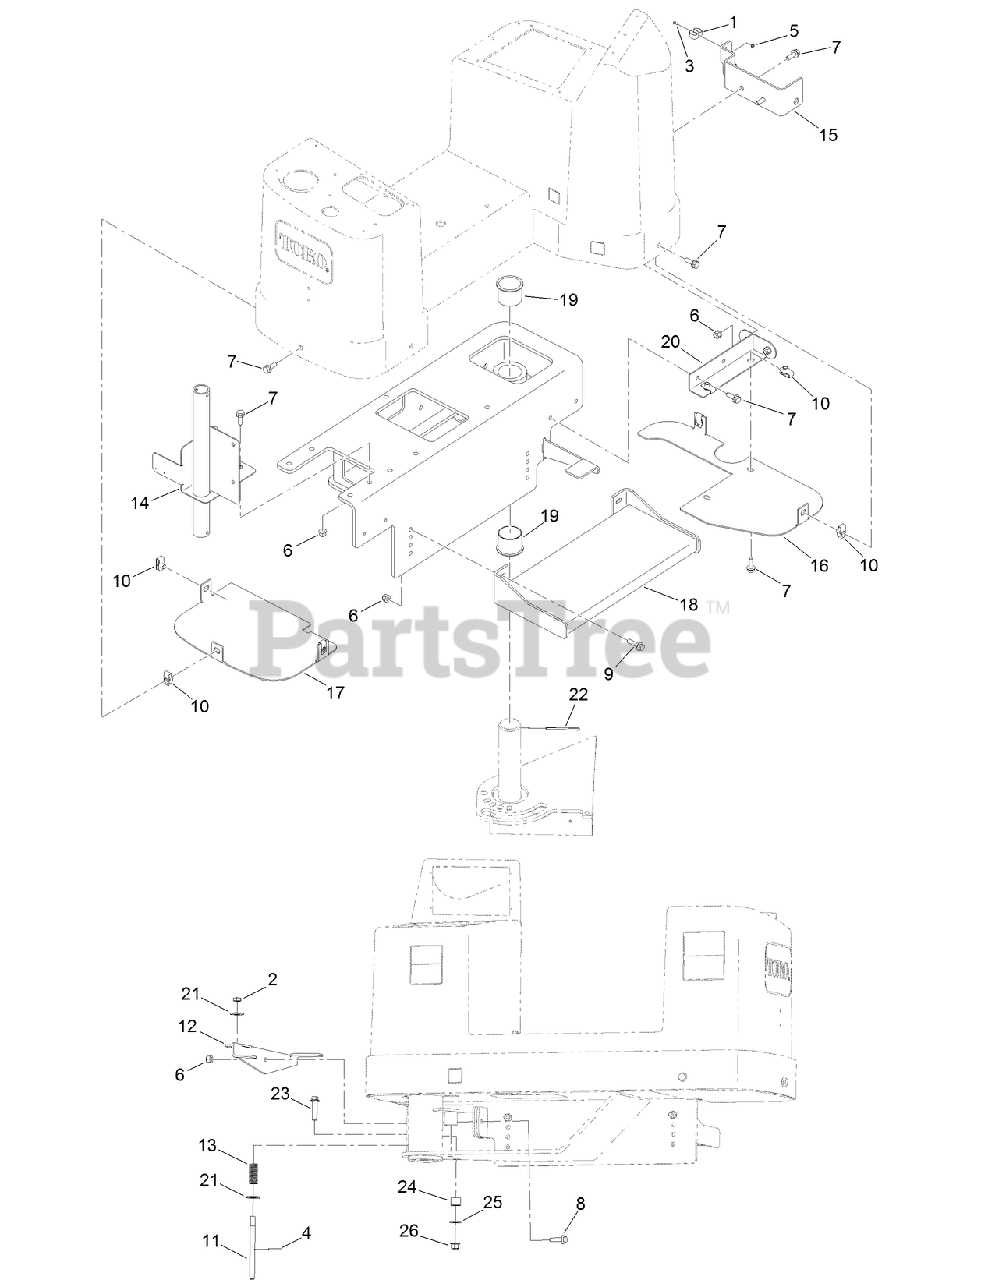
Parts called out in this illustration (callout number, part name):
1	CLIP-SPRING
2	NUT-JAM
3	SCREW-PRH
4	PIN-COTTER
5	NUT-KEPS
6	NUT-LOCK, NI
7	SCREW-HHF
8	SCREW-HHF
9	SCREW-HHF
11	ROD-SWING, SEAT
12	ARM-ADJUSTMENT, SEAT
13	SPRING-PIVOT LOCK, SEAT
14	MOUNT-UMBRELLA
15	PLATE-RETAINING, CORD
16	PLATE-GUARD, SPLASH
17	PLATE-GUARD, SPLASH
19	BEARING-FLANGED
20	SUPPORT-SHROUD, LEFT
21	WASHER-FLAT
22	PIN-COTTER
23	SCREW-HHF
24	SPACER
25	WASHER-FLAT
26	NUT-LOCK, HHF
